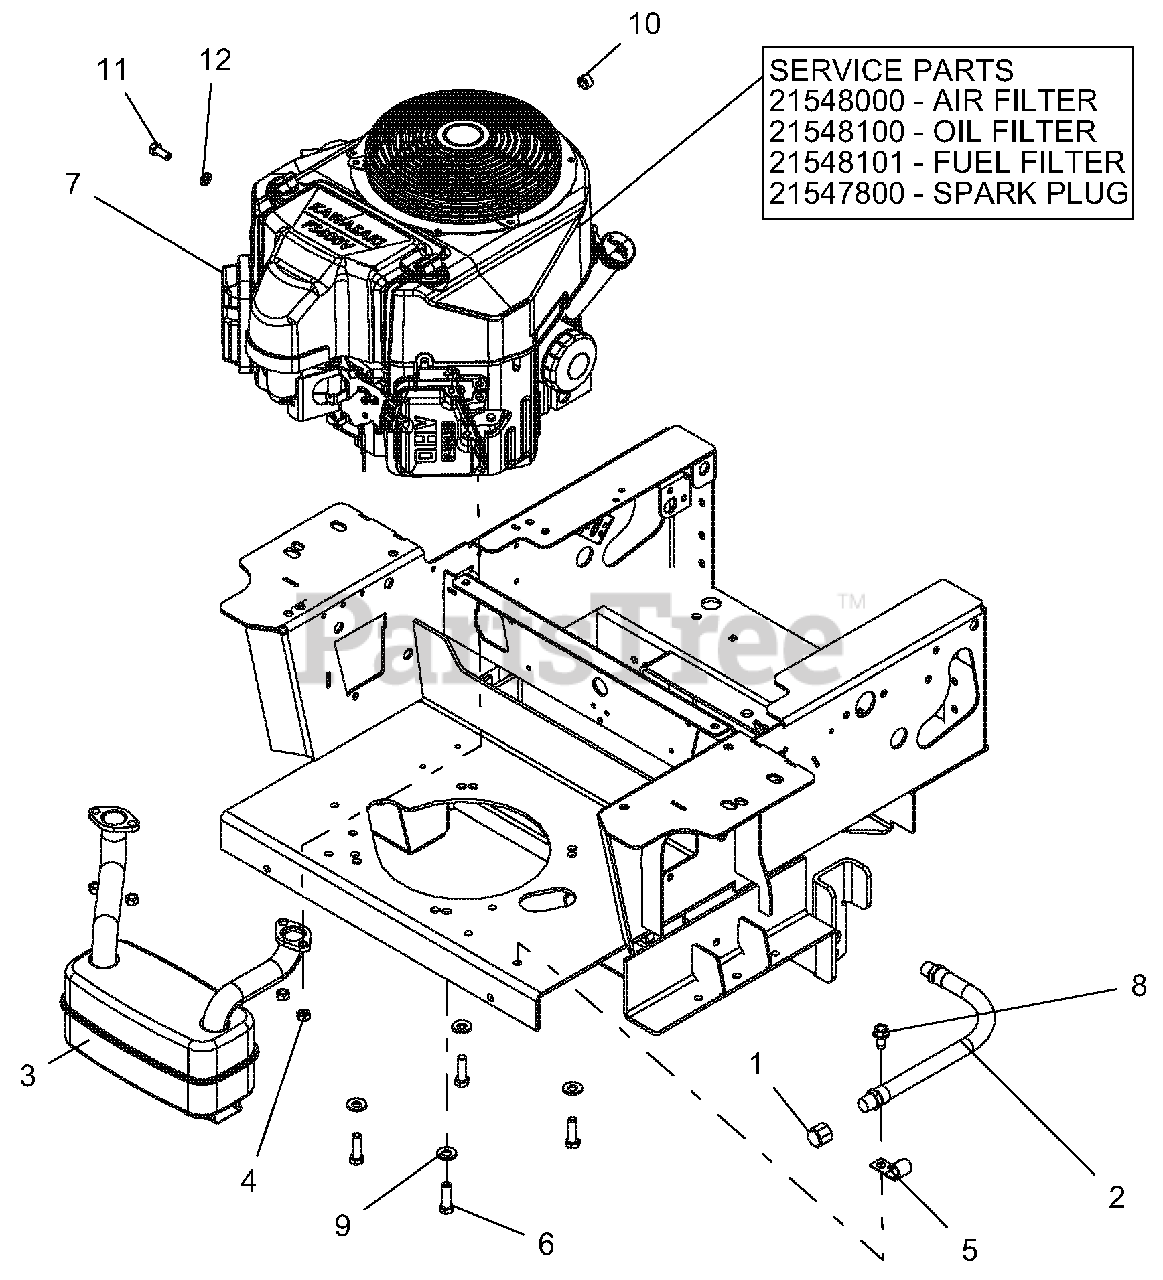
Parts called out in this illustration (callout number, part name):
1	PIPE, CAP 3/8 NPT FEMALE
2	HOSE, HYD .38-11-OK M6N0-M6N0
3	MUFFLER, KAWASAKI
4	NUT-LK-TOP M8-1.25 YWZC
6	BLT-HEX .38-16X1.25 GR5 YWZC NYTORQ
7	ENGINE, KAWASAKI FS691
7	AIR FILTER
7	OIL FILTER
7	FUEL FILTER
7	SPARK PLUG
8	SCR-TAP .38-16X.75 HWH TR YWZ
9	WSHR, 3/8" SPRING DISC
10	CLAMP, FUEL LINE
11	@BLT-HEX M8-1.25X20 YWZC
12	WSHR-LK .31X.078 REG YWZC
